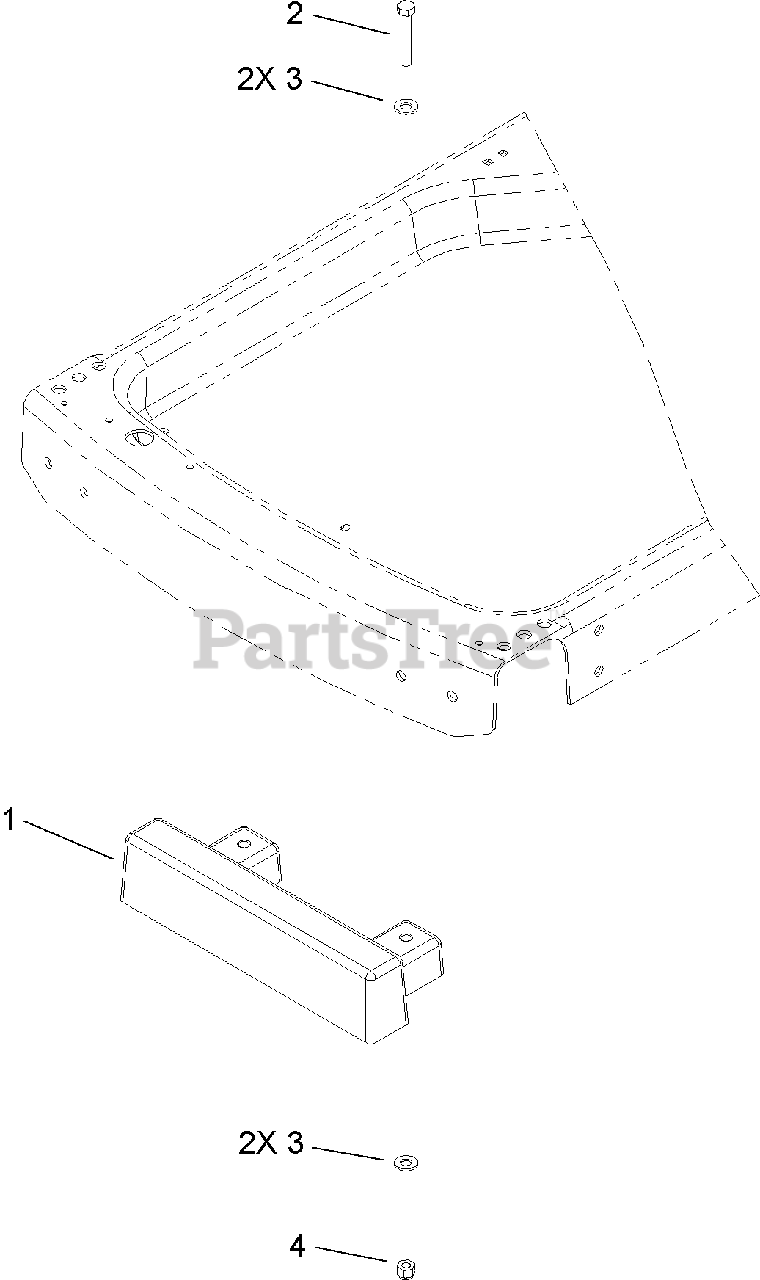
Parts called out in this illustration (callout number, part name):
1	WEIGHT-BAGGER
2	SCREW-HH
3	WASHER-FLAT
4	NUT-LOCK, NI
